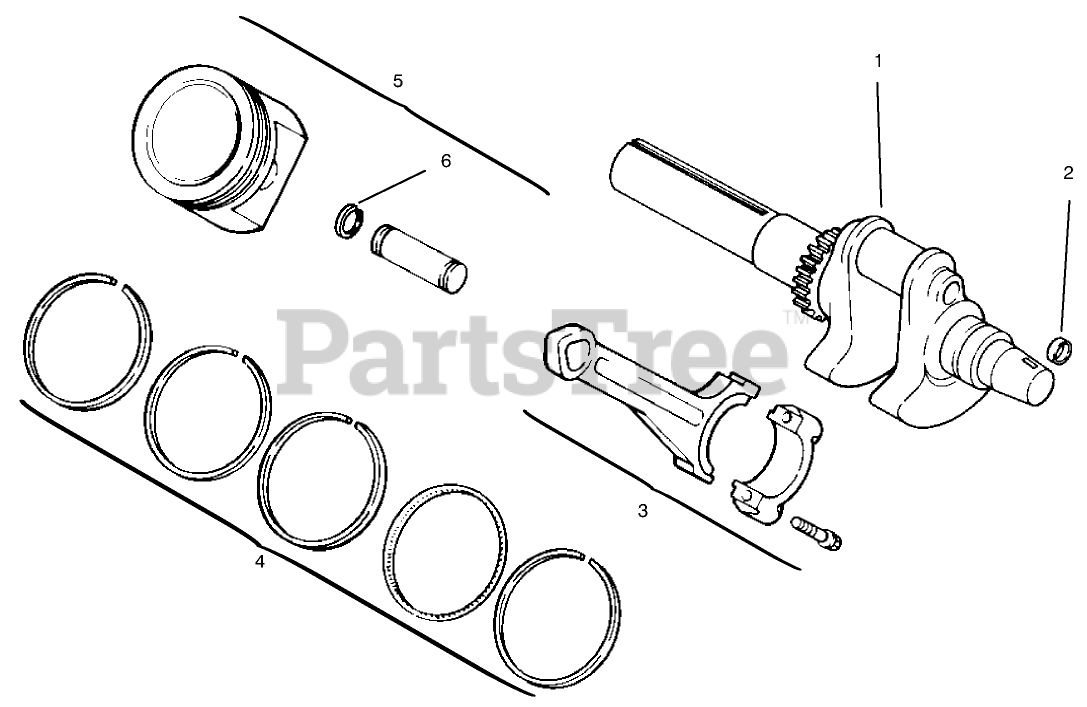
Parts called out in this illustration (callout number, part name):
1	Crankshaft
2	Plug-Cup
3	Connecting Rod STD
4	Ring Set(Std.)
5	Piston w/Ring Set (Std.) (Incl. Ref. # 4-6)
6	Retainer-Piston Pin
